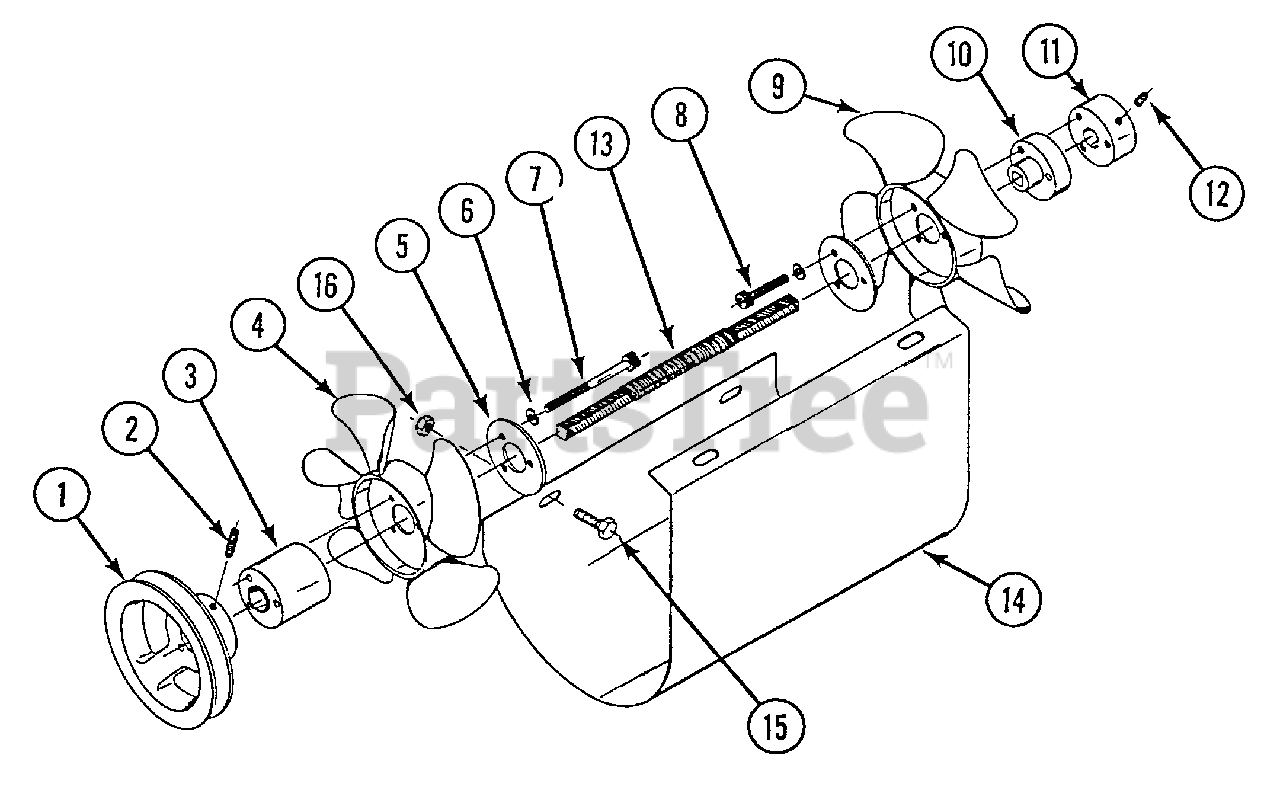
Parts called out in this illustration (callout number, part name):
1	HYDRO DRIVEN PULLEY, 5"
1	HYDRO DRIVEN PULLEY, 5-1/16 JOYSTICK
2	SKHD SETSCREW, 1/4-20 X 3/4 W/NYLOC
3	CONNECTOR, LEFT
4	FAN BLADE, 8" CCW - 3 HOLES
5	WASHER, SPECIAL FOR FAN BLADE
6	LOCKWASHER, 1/4 STD, SPLIT SPRING
7	CAPSCREW, SOCKETHEAD, 1/4-20 X 2-3/4
8	CAPSCREW, SOCKETHEAD, 1/4-20 X 1-1/4
9	FAN BLADE, 8" CW - 3 HOLES
10	RIGHT CONNECTOR-COUPLING SHAFT
11	RIGHT CONNECTOR COUPLING HYDRO
12	SETSCREW, 1/4-20 X 5/16 SOCKET HEAD
13	COUPLING SHAFT, 5/8" FLEXIBLE
14	AIR DEFLECTOR SHROUD
14	AIR DEFLECTOR SHROUD, JOYSTICK
15	CAPSCREW, 5/16-18 X 1 HEXHEAD GRADE 5
16	LOCKNUT, 5/16-18 HEX W/NYLOCK
